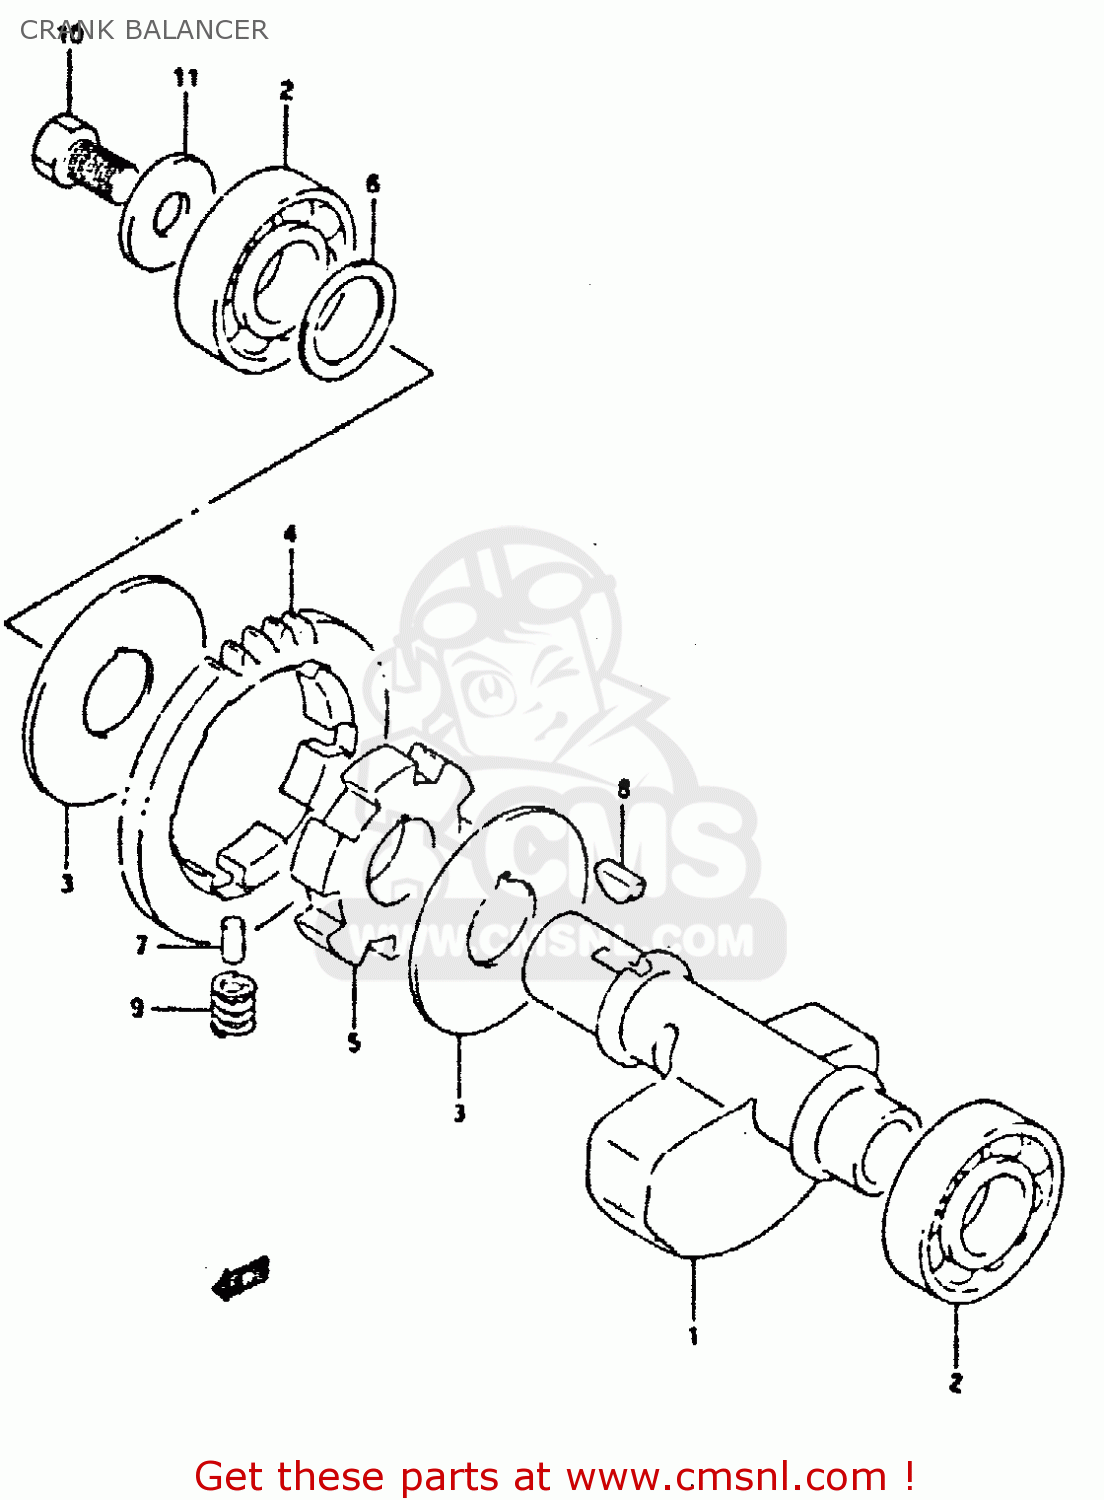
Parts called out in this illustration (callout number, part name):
1	SHAFT,CRANK BALANCER
2	BEARING(20X47X14)
3	WASHER
4	GEAR,CRANK BAL DRIVEN(NT:37)
5	RACE,CRANK BALANCER DRIVEN GEAR
6	THRUST WASHER
7	PIN(4.5X9.5)
8	KEY
9	SPRING
10	BOLT
11	WASHER
